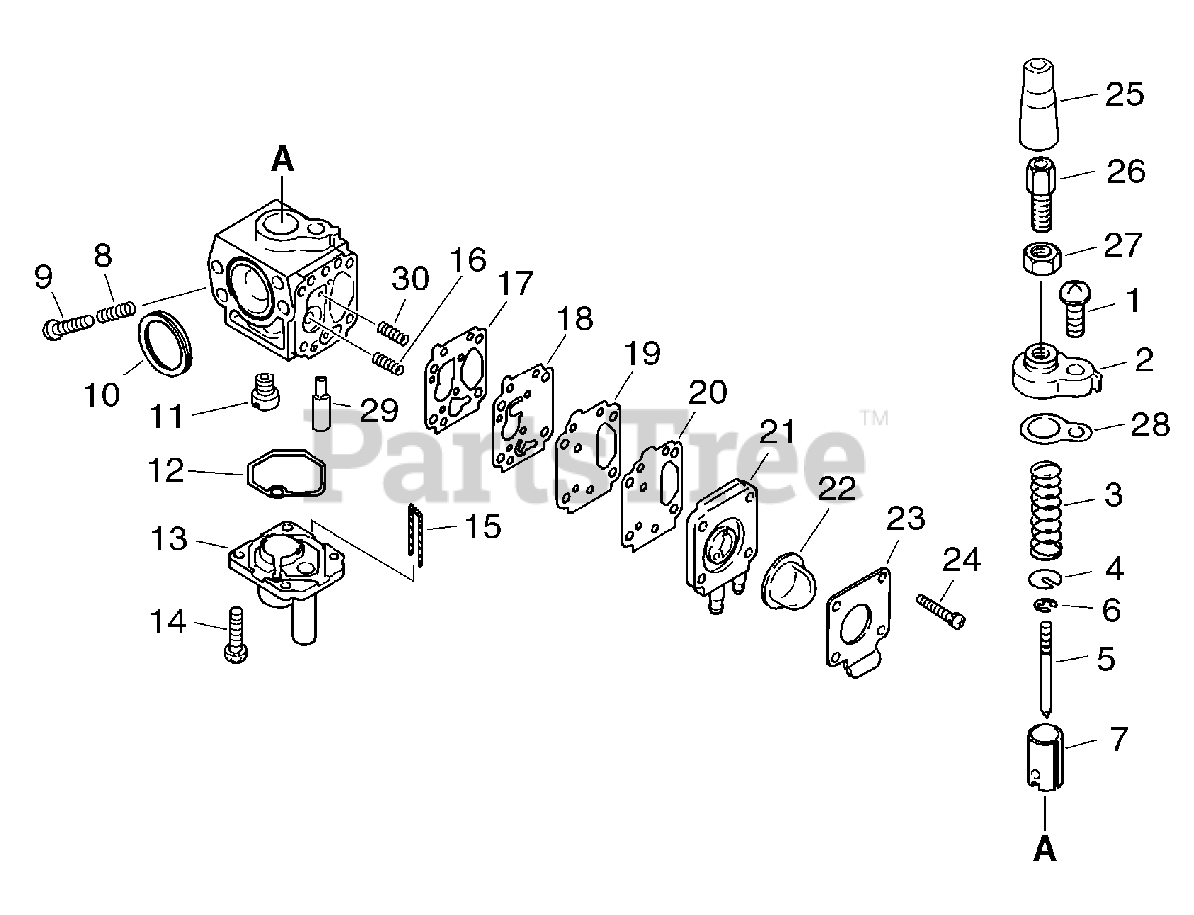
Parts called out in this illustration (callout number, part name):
2	COVER, VALVE
3	SPRING, THROTTLE
4	WASHER, SPRING SUPPORT
5	NEEDLE, JET
7	VALVE, THROTTLE
9	SCREW, IDLE ADJUST
10	RING, PACKING
11	JET, MAIN #44
12	GASKET, CHAMBER
13	CHAMBER, FLOAT
14	SCREW 3×10
15	WIRE, DRAIN
17	GASKET, FUEL PUMP
18	DIAPHRAGM, FUEL PUMP
19	PLATE, FUEL PUMP
20	GASKET, FUEL PUMP
21	BODY ASSY, PUMP
22	BULB, PURGE
23	COVER, FUEL PUMP
24	SCREW M3×14
25	CAP, RUBBER
26	ADJUSTER, CABLE
27	NUT, LOCK
28	NEEDLE, JET
